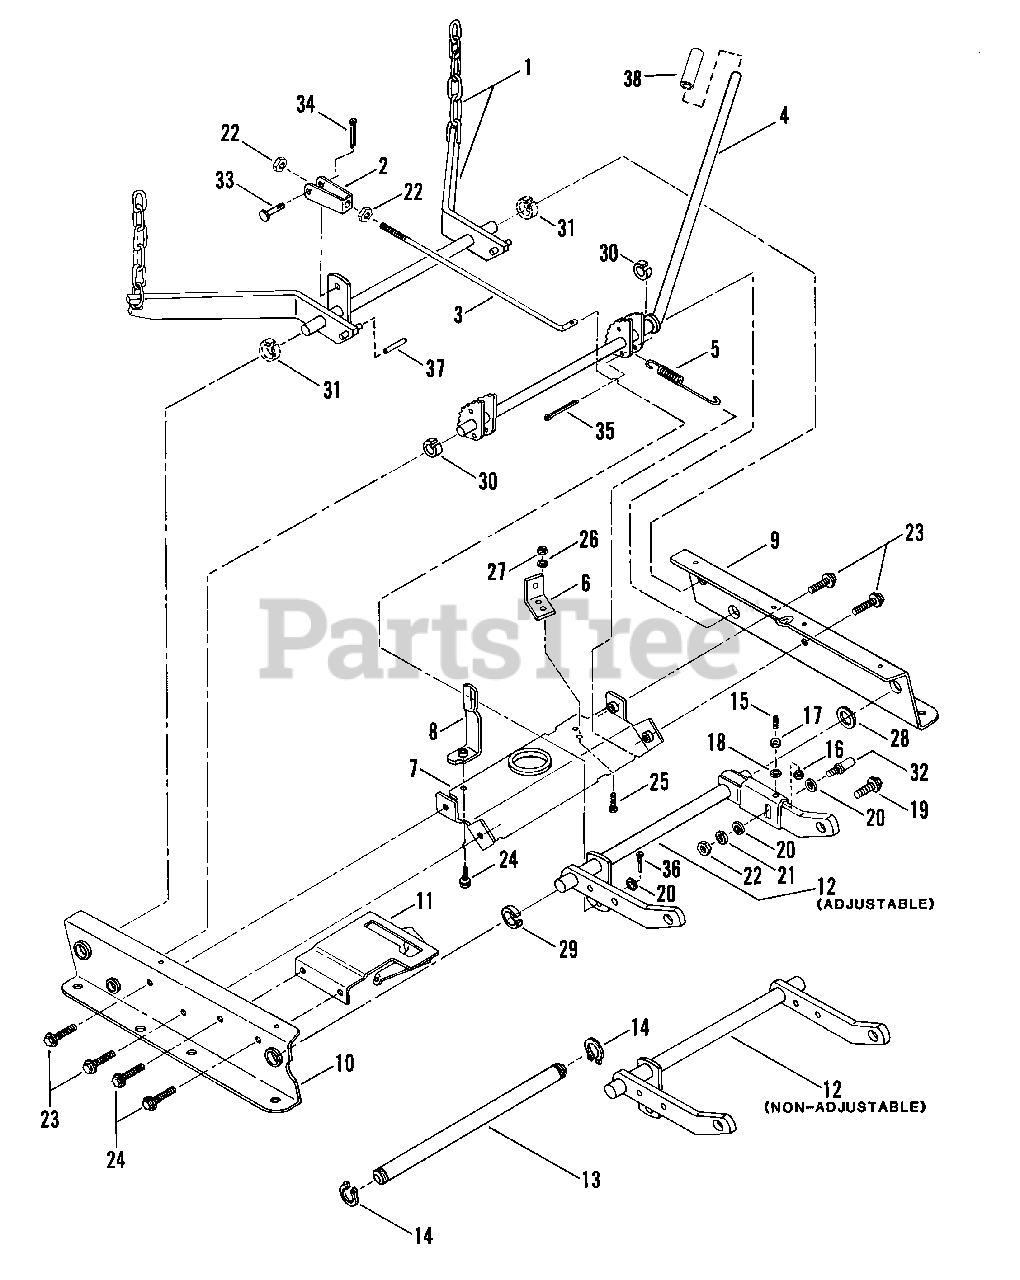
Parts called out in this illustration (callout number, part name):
1	REAR LIFT ARM ASSY
2	CLEVIS, Timing Rod
3	TIMING ROD
4	CAM LIFT LEVER
5	SPRING, Cam Lift
6	ANCHOR
7	BRACE, Top
8	GUIDE, Belt
9	RAIL, Left Hand
10	RAIL, Right Hand
11	CLUTCH-PLATE
12	FRONT LIFT ARM
13	SUPPORT ROD
14	RING, 5/8" External Retaining
15	SETSCREW, 5/16-18x1 1/4" Hex Socket
16	NUT, 5/16-18 Hex
17	JAM-NUT, 5/16-18 Hex
18	WASHER, 5/16 SAE
19	CAPSCREW, 3/8-24x1 1/4" Hex Head
20	WASHER, 3/8 SAE
21	LOCKWASHER, 3/8 Split
22	NUT, 3/8-24 Hex
23	SCREW, 3/8-16x1" Hex Self-Tap
24	SCREW, 5/16-18x5/8" Hex Self-Tap
25	SCREW, 5/16Fx3/4" Hex Head Cap
26	LOCKWASHER, 5/16 Internal Tooth
27	NUT, 5/16F Hex
28	WASHER
29	RING, Red
30	RING, White
31	RING, Blue
32	PIN, Shoulder Bolt
33	PIN, 3/8 x 1 1/16" Clevis
34	PIN, 3/32x3/4" Cotter
35	PIN, 5/32x1" Cotter
36	PIN, 1/8x3/4" Cotter
37	PIN, Roll
38	GRIP, Height Adjustment Lever
